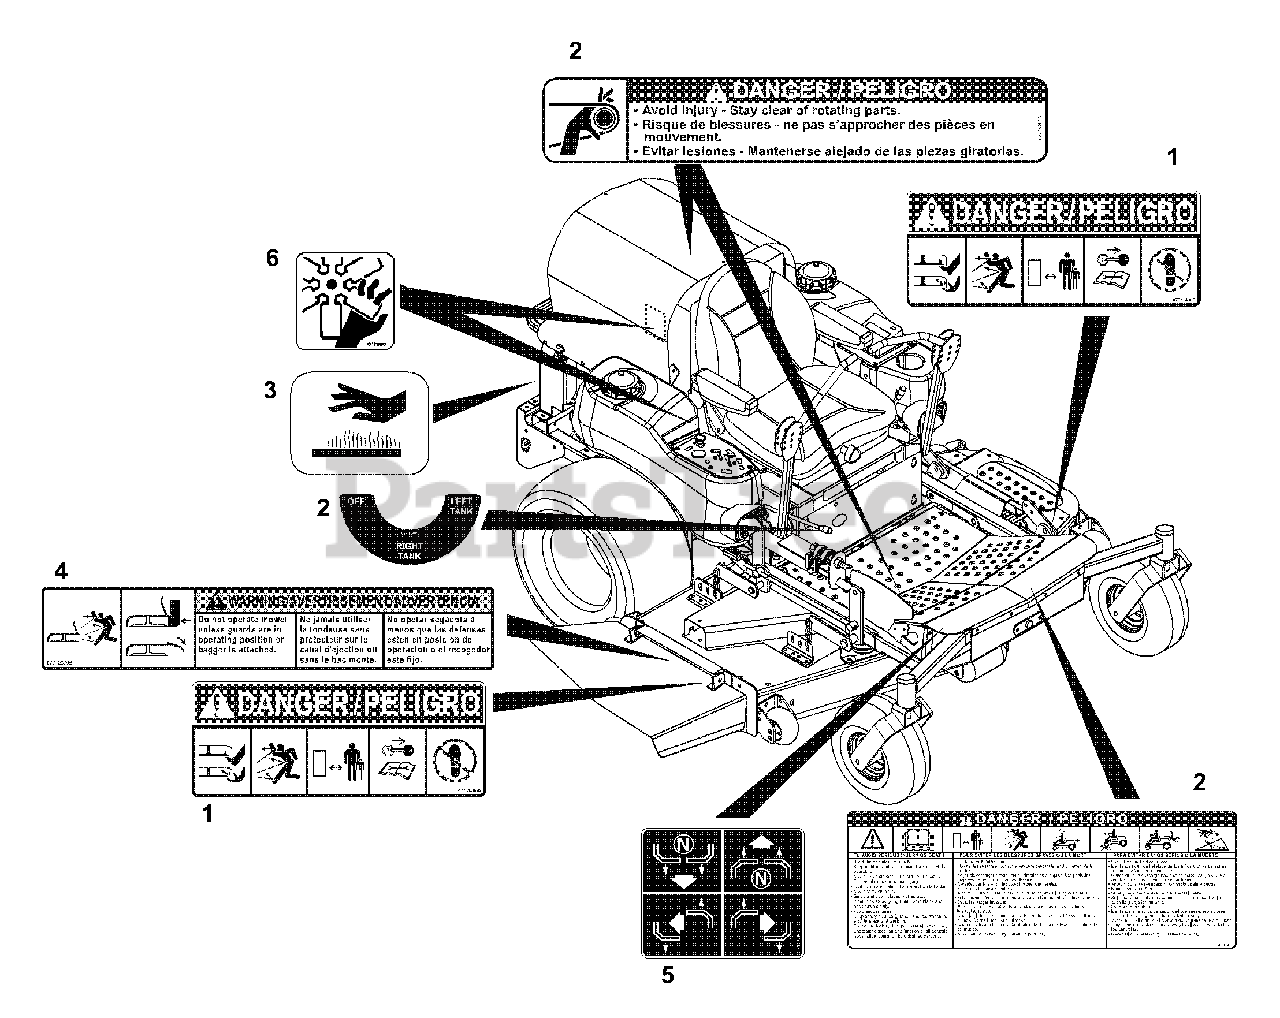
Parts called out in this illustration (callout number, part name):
1	DECAL, MOWER PAN DANGER
2	SET, DECAL-COMMON DANGER/FUEL
3	DECAL, HOT SURFACE
4	DECAL, WARNING
5	DECAL, INSTRUCTIONAL-STEERING
6	DECAL, DANGER FAN
